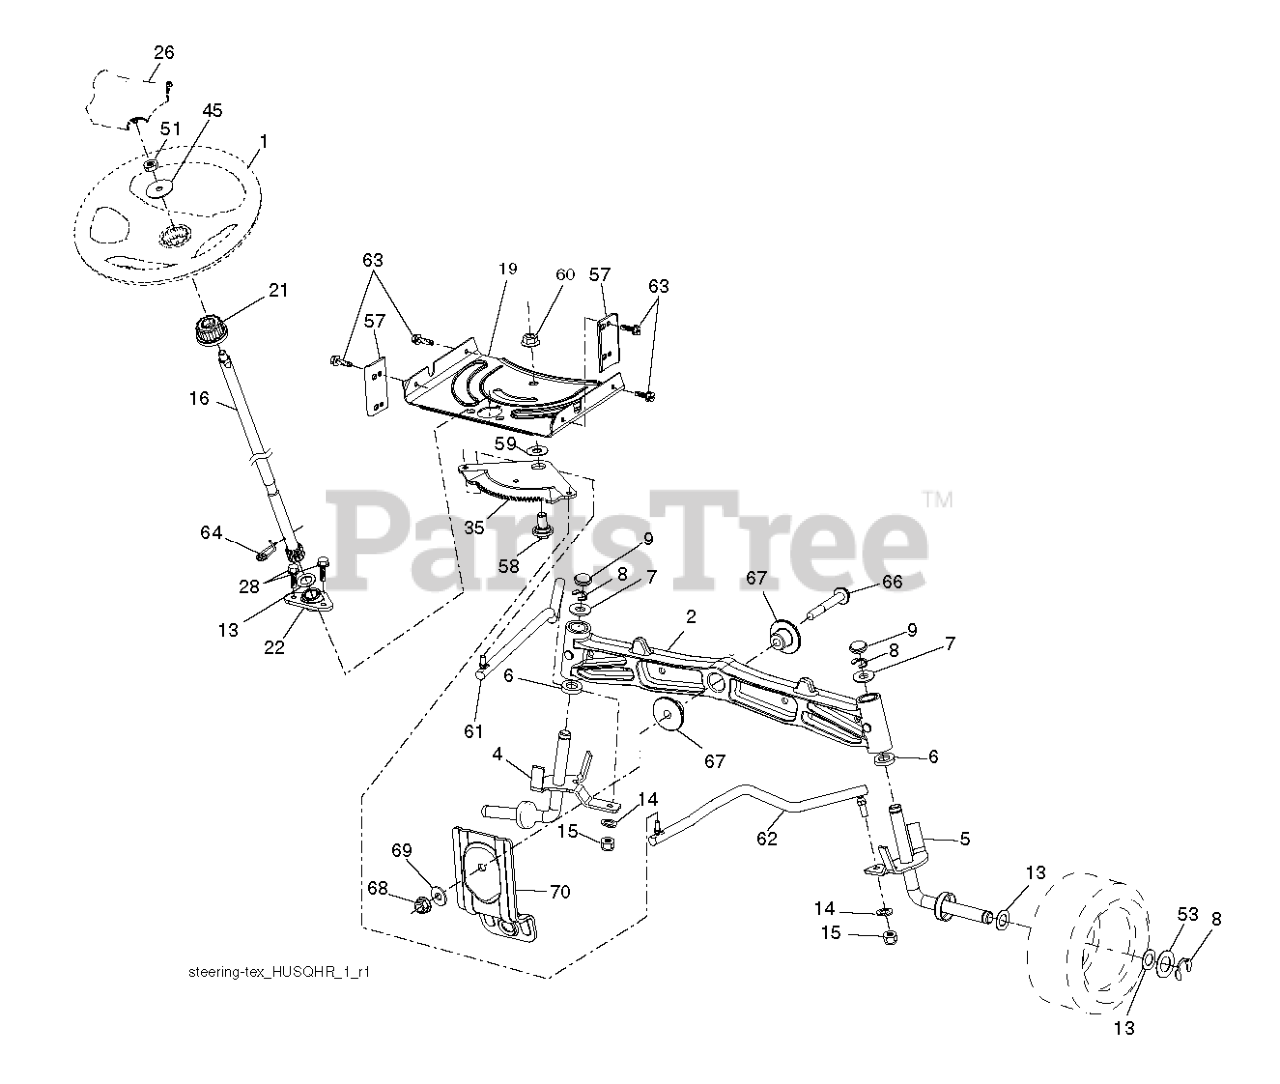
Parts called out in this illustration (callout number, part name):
1	RP WHEEL.STEER.HUSQ.PREM.OVMLD
2	AXLE.CAST.IRON
4	SPINDLE.WELDED.LH.15"TEX
5	SPINDLE.WELDED.RH.15"T
6	THRUST WASHER
9	CAP.SPINDLE.BLACK
14	WASHER, LOCK 3/8
15	NUT CROWNLOCK 3/8-24
16	SHAFT, STEERING
19	PLATE.STEER.DDL.NLT/NG
21	ADAPTER, WHEEL STNG..
22	STEERING.SUPT.LOWER.
26	RP INSERT.CAP.WHL.STRG.HUSQ.
28	SCREW, 3/8-16X3/4
35	GEAR.SECTOR.PLATE.DDL.
45	WASHER 9/16"ID, 2 3/8"OD
51	NUT.HEX.1/2-20
53	WASHER.HARDENED
57	BRACKET.UPSTOP.TEX
58	BOLT.SHOULDER.SECTOR.P
59	WASHER.THURST.SECTOR.S
60	NUT FLANGE LOCK 5/8-11
61	DRAGLINK.LH.BALLSTUD.D
62	DRAGLINK.RH.BALLSTUD.D
63	SCREW
64	RETAINER.CLIP.SPRING.S
66	BOLT HEX FGHD 7/16-14 X 3 SERR
67	BUSHING.PM.FRONT AXLE
68	NUT.LOCK.FLANGE.7/16
69	WASHER.1.5X.505X.118
70	BRKT.DECK.SUSPENSION.F
